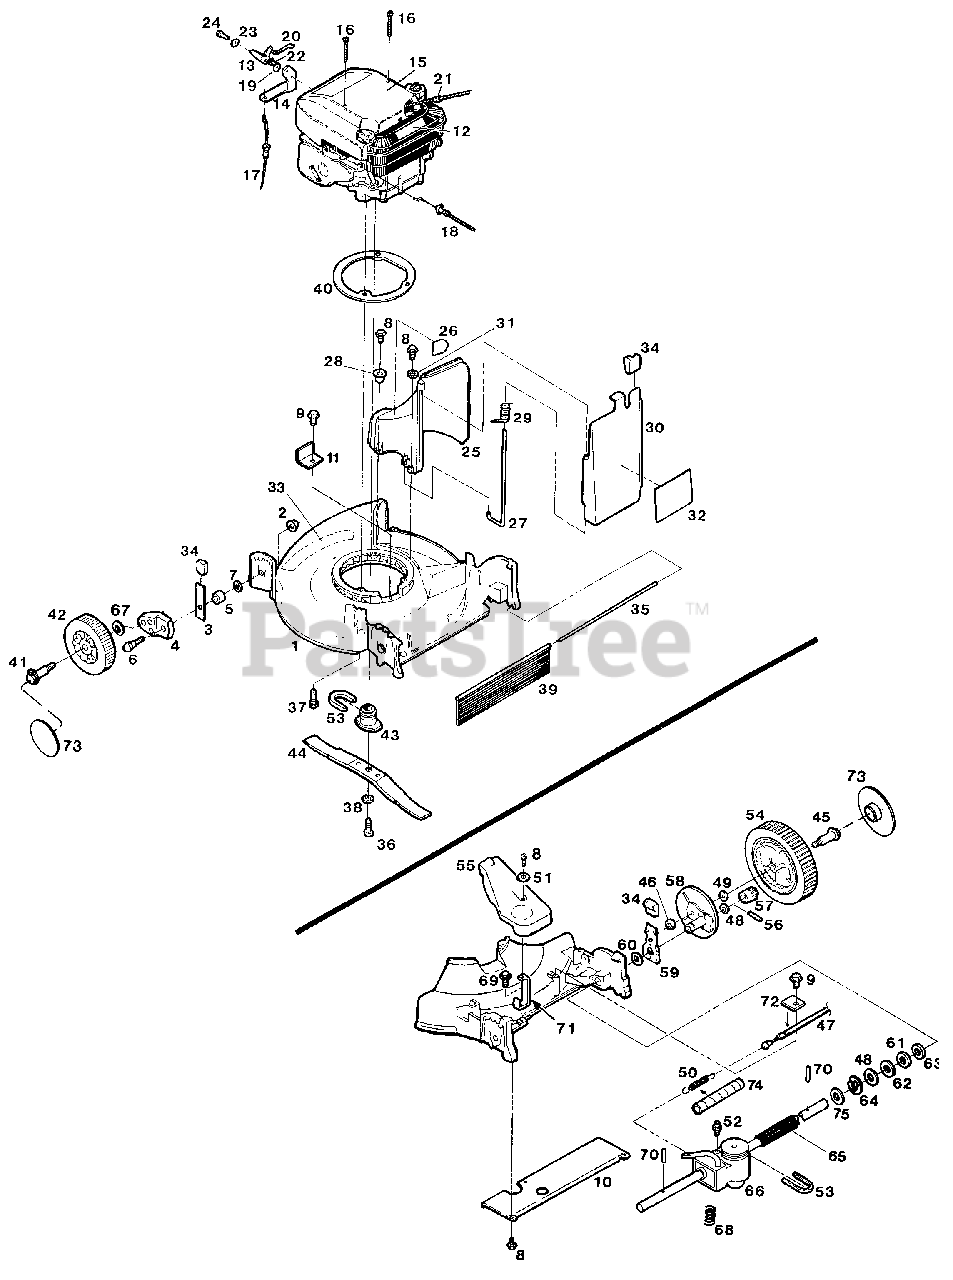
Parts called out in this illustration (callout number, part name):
1	DECK - 21" Propelled
2	NUT - 5/16" Flg Lock
3	SETTING LEVER ASSY
4	ARM - Wheel mount
5	SPACER - WHEEL
6	BOLT - Height Adjuster
7	WASHER - 5/16" Flat
8	SCREW - 1/4-20 x 3/4" Hex Tap
9	SCREW - 1/4-20 x 1/2" Hex Tap
10	COVER - Rear
11	COVER - Belt Opening
12	DECAL - Blade Warning BI/FR
13	BELLCRANK
14	BRACKET - Throttle
15	COVER ENGINE
16	SCREW - #8-32 x 1-1/4" Phil Tap
17	CONTROL - Throttle w/Cable
18	CABLE - Engine/Blade Control
19	SPACER - Stepped
20	LINK - throttle
21	ROPE STOP
22	SCREW - #10-24 x 3/8" Hex Tap
23	WASHER - 3/16" flat
24	SCREW - #10-24 x 3/4" Hex Tap
25	DISCHARGE CHUTE
26	DECAL - CPSC DANGER
27	HINGE PIN
29	SPRING - Door Chute
30	DOOR - Chute
31	WASHER - 1/4" Flat
32	DECAL - Door Warning
33	DECAL - Logo 21"
34	PLASTIC TIP - Height Adjuster
35	ROD - Trailing Shield
36	BOLT - 3/8-24 x 1-1/4" HHCS GR8
37	BOLT - 3/8-16 x 2-1/4" Sems
38	WASHER - 3/8 Lock H.D.
39	TRAILING SHIELD - Plastic
40	ENGINE RING
41	BOLT - wheel
42	WHEEL - 8"
43	BLADE ADAPTER - 7/8" DIA. PP
44	BLADE - 21"
45	BOLT - wheel
46	NUT 3/8-16 Flg Lock
47	CABLE - Drive Control
48	WASHER - 5/8" x 22 GA. Hard
49	WASHER - 3/8" Flat
50	SPRING - Extension
51	WASHER - 1/4" Flat
52	VENT - Transmission
54	WHEEL - 8" w/gear
55	COVER - Drive
56	DRIVE PIN
57	PINION R.H.
58	DRIVE WHEEL SUPPORT Assy
59	SETTING LEVER - rear
60	SPACER - Rear adjuster
61	WASHER - 5/8" x 22 GA. Hard
62	WASHER - 5/8" x 14 GA. Flat
63	WASHER - 5/8" Wave
64	E-RING - 5/8"
65	COVER - Drive Shaft - 8 1/4"
66	TRANSMISSION - 1 spd
67	WASHER - Belleville
68	SPRING - Compression
69	SCREW - #10-16 Hex Tap
70	ROLL PIN - 1/8 x 7/8
71	BRACKET - Belt Cover
72	CLAMP - Drive Control Cable
74	COVER - Spring
75	WASHER - Thrust
